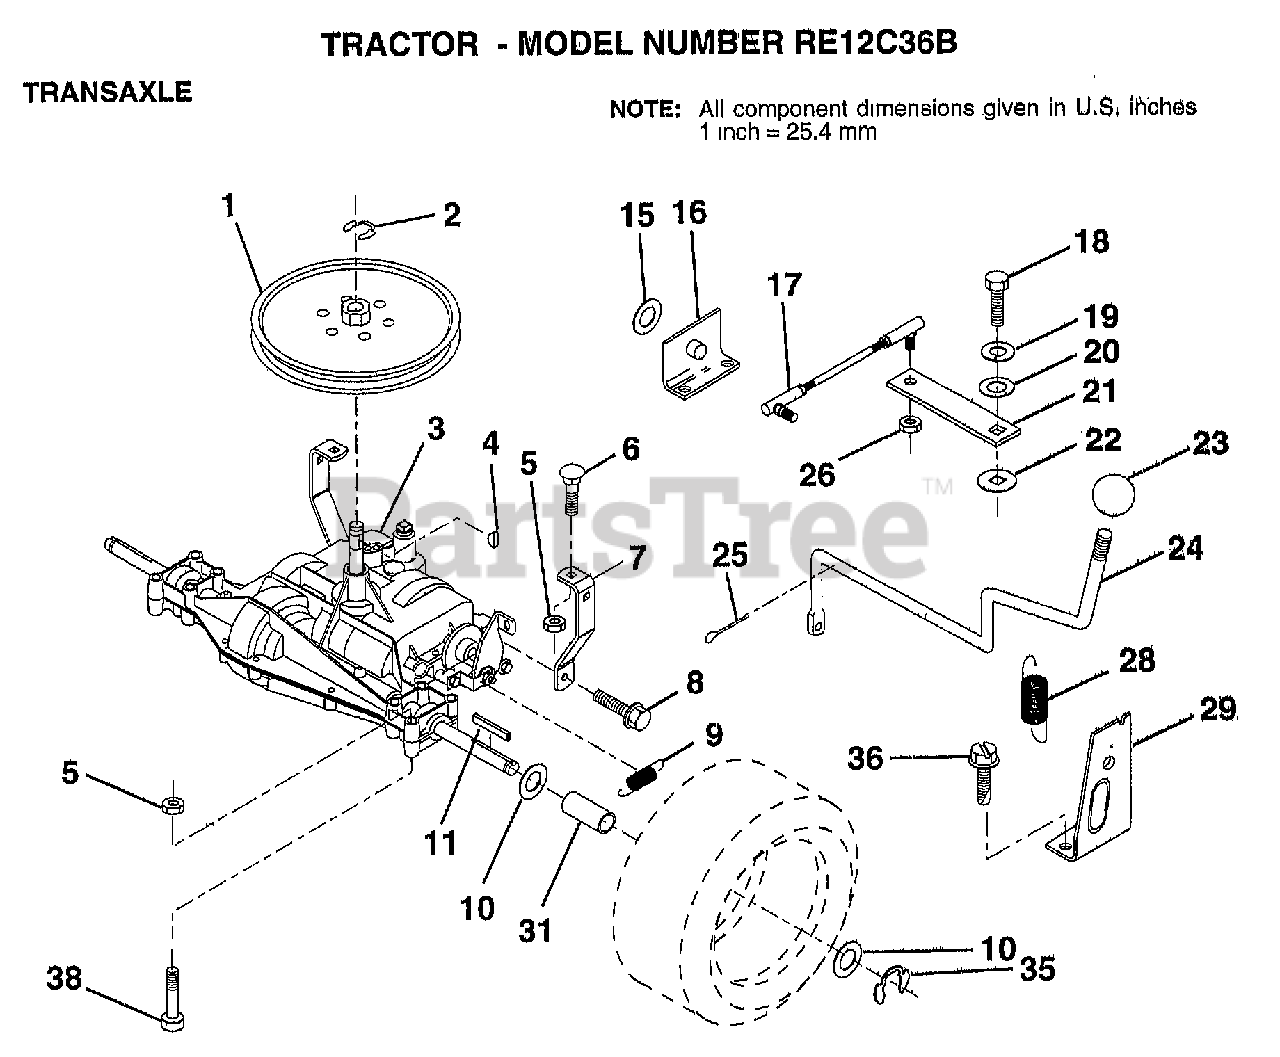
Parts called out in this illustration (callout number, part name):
1	PULLEY
6	BOLT
7	"STRAP,TORQUE"
8	SCREW
9	SPRING.BRAKE.RETU
10	WASHER
11	SQUARE KEY
16	"SUPT,HDLE SHT LH"
17	LINK SHIFT
18	BOLT.1/4-28.W/PAT
19	LOCKWASHER
20	WASHER LT
22	WASH-SHFT PLT LT
23	KNOB T (1/2-HOLE)
24	"ROD,SHIFT"
25	PIN COTTER 1/8
26	NUT.LOCK.5/16-24
28	"SPRING,EXT"
29	"SUPT,HDLE RH"
31	SPACER AXLE
35	E-RING LT
36	SCREW
38	BOLT.HEX.FLGHD
